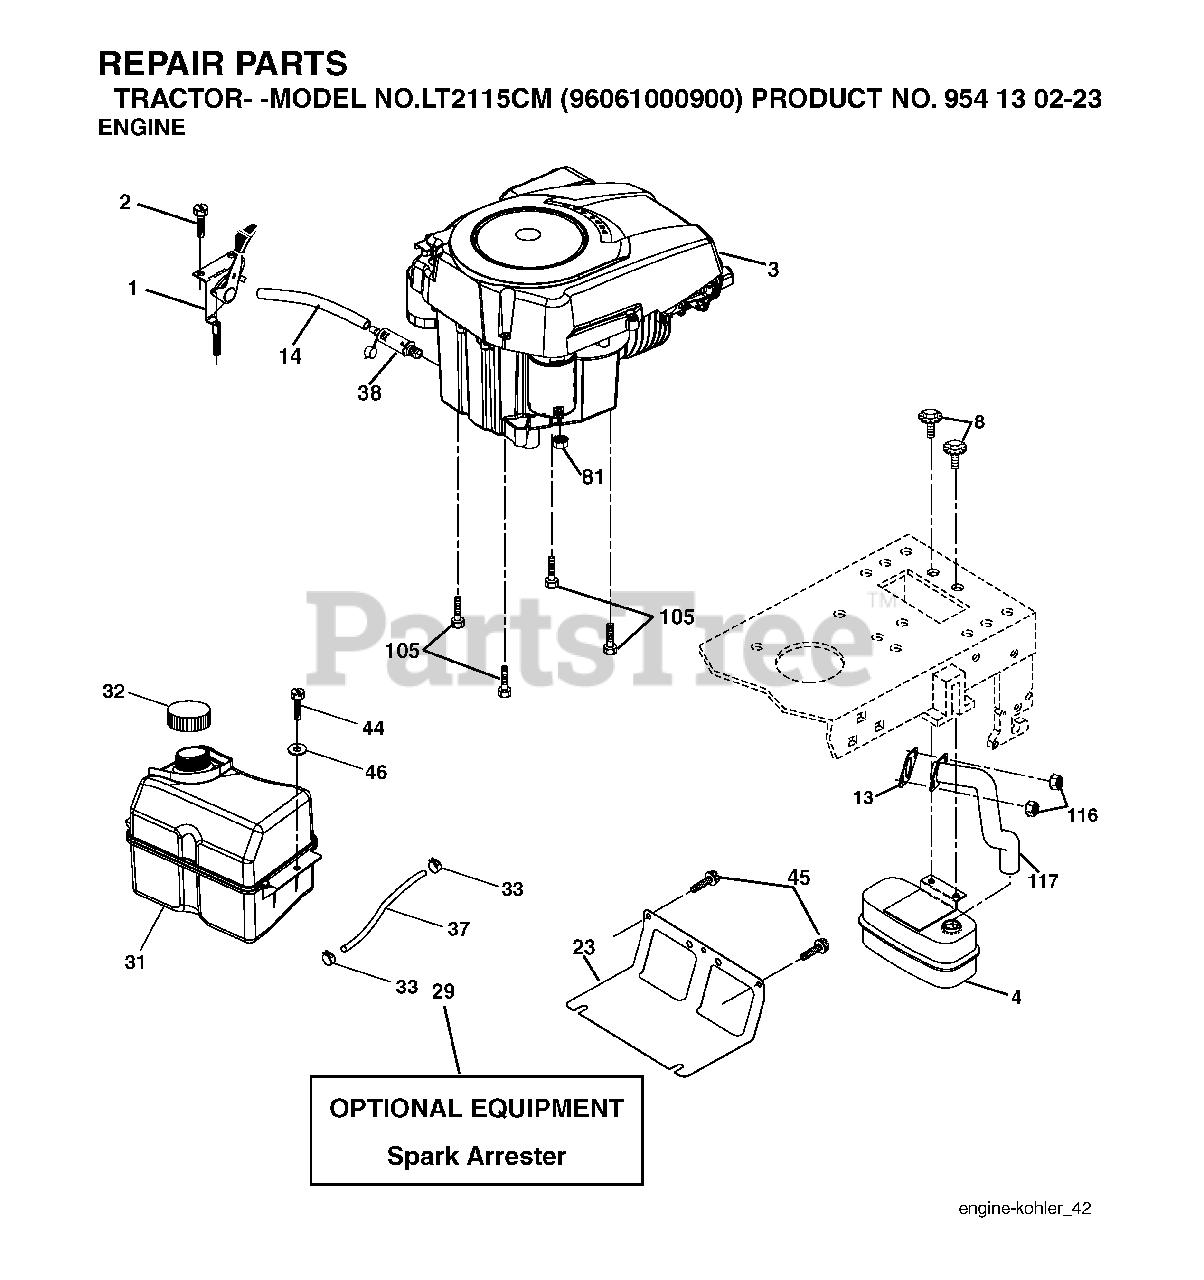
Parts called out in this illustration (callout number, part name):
1	CONTROL.THROTTLE.LT/YT
2	SCREW
4	MUFFLER.SINGLE.CYL.KOHL/B&S
8	BOLT, 5/16-18 X 1 3/4
13	GASKET ENGINE
14	TUBE, DRAIN OIL ASM.
23	SHEILD.BROWNING.DBR.GUARD
29	ARRESTER SPARK (OPTIONAL)
31	TANK FUEL
32	FUEL CAP
33	HOSE CLAMP
37	LINE.FUEL.20
38	PLUG DRAIN OIL EASY
44	SCREW HEXWSHR 1/4-20X3/4
45	SCREW, 3/8-16X3/4
81	NUT
105	SCREW 3/8-16X1
116	NUT.HEX.FLANGE.TOPLOCK
117	TUBE EXHAUST
